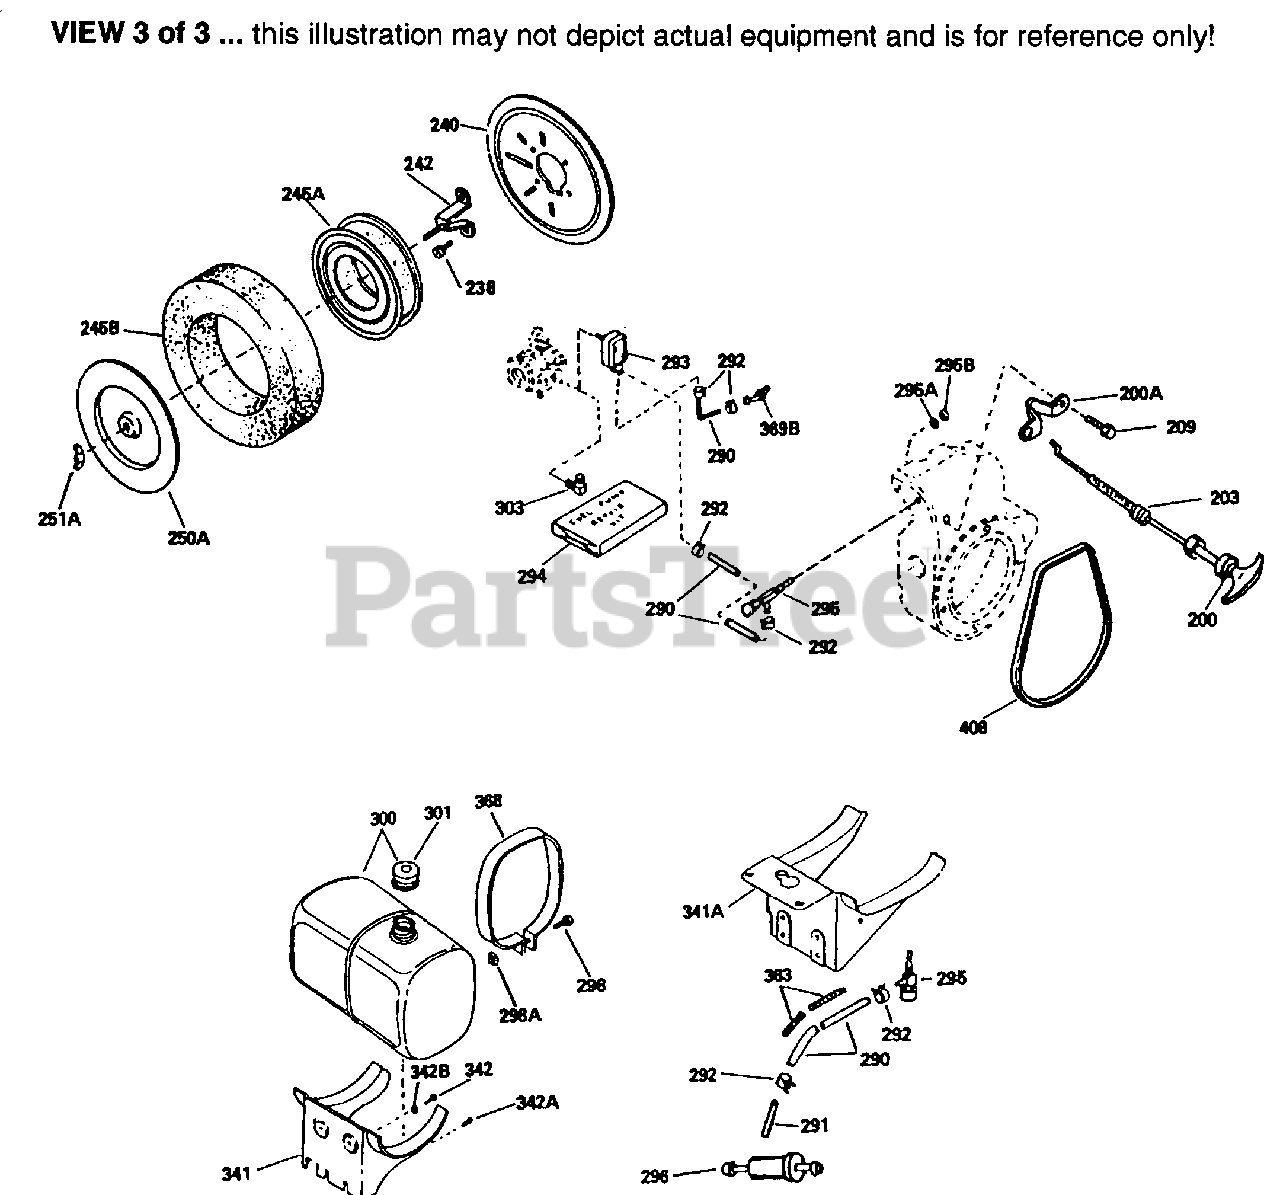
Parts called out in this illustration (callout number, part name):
3	Screw, 5/16-18 x 1/2"
16B	Governor Spring Plate
46	Connecting Rod Bolt
50	Camshaft (MCR)
65	Screw, 10-24 x 1/2"
80	Governor Shaft
84	Retaining Ring
92	Lock Washer
149A	Valve Spring Cap (1/32" OS Stem)
149C	Valve Pin
238	Screw, 10-32 x 5/8"
242	Air Cleaner Bracket
242A	Air Cleaner Bracket
260	Blower Housing
265	Cylinder Head Cover
290	Fuel Line
292	Fuel Line Clamp
295	Fuel Shut Off Valve
298	Screw, 1/4-20 x 1"
298A	Lock Nut, 1/4-20
298B	Screw, 5/16-18 x 5/8"
298C	Washer
300	Fuel Tank
323A	Terminal
341	Fuel Tank Bracket
342	Screw, 1/4-20 x 5/8"
355	Starter Handle
368	Fuel Tank Strap
